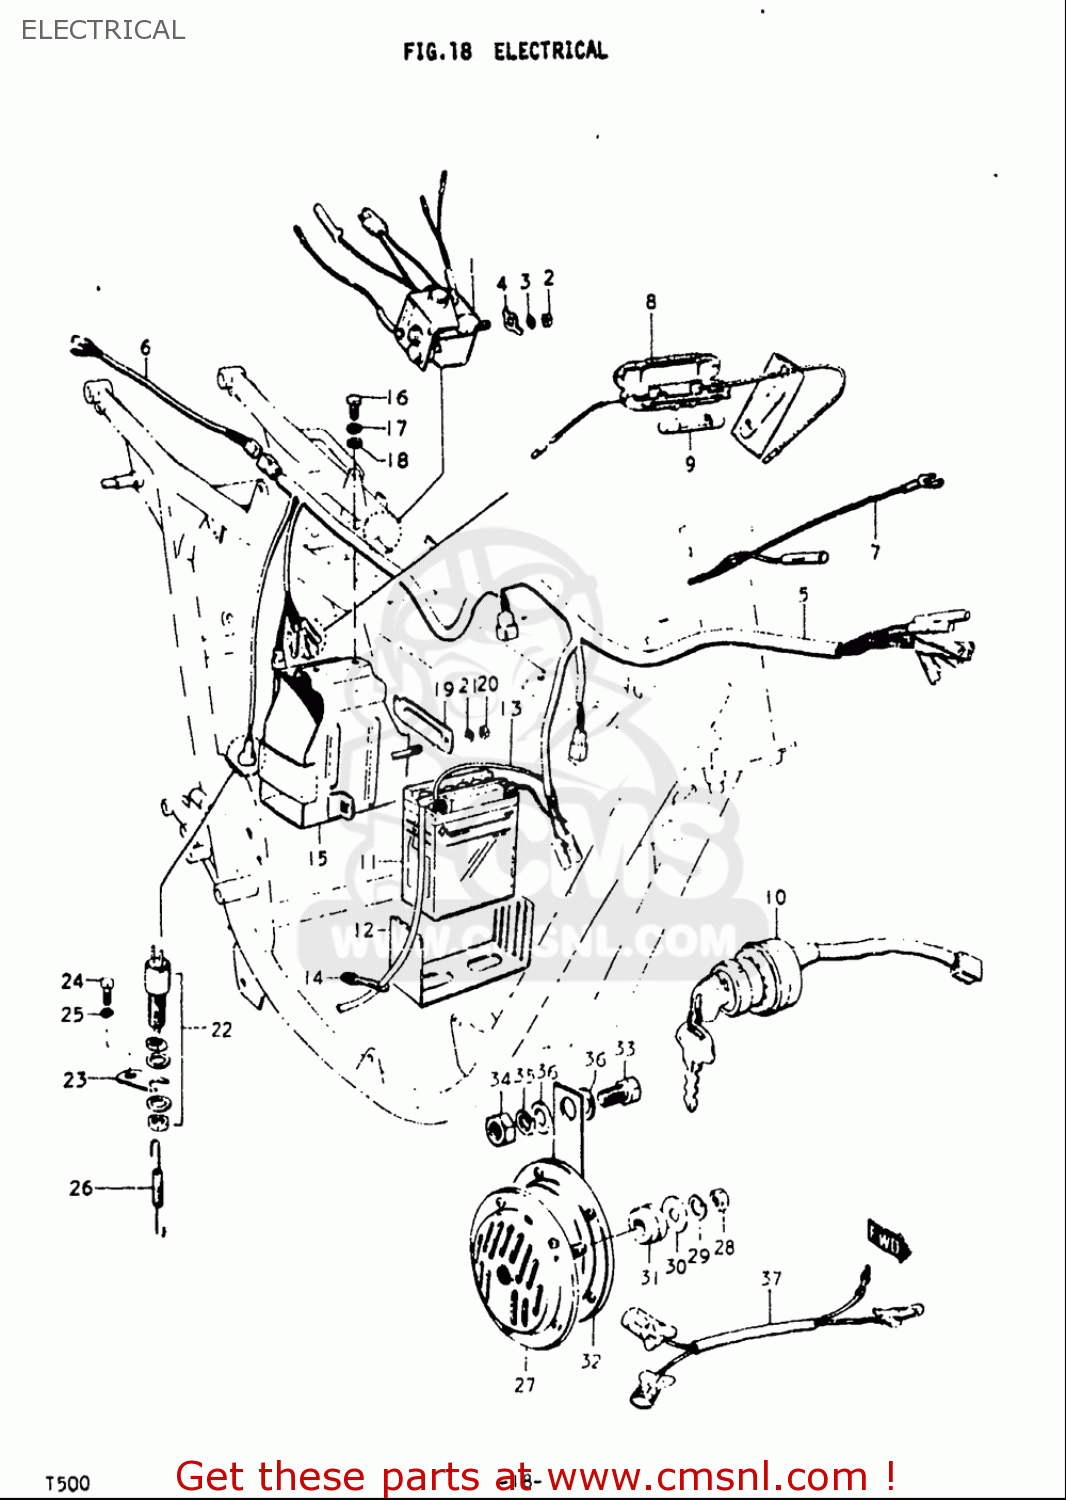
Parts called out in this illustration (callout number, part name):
1	RECTIFIER ASSY
2	NUT
3	WASHER,LOCK
7	CORD, HANDLEBAR EARTH
8	CASE ASSY,FUSE
9	FUSE(15A)
13	LEAD WIRE
16	BOLT
17	WASHER,LOCK
18	WASHER(8.5X18X2)
20	NUT
21	WASHER,LOCK
22	SWITCH ASSY,BRAKE LAMP
24	BOLT
25	WASHER,LOCK
26	SPRING
28	NUT
29	WASHER,LOCK
33	BOLT
34	NUT
35	WASHER,LOCK
36	WASHER
